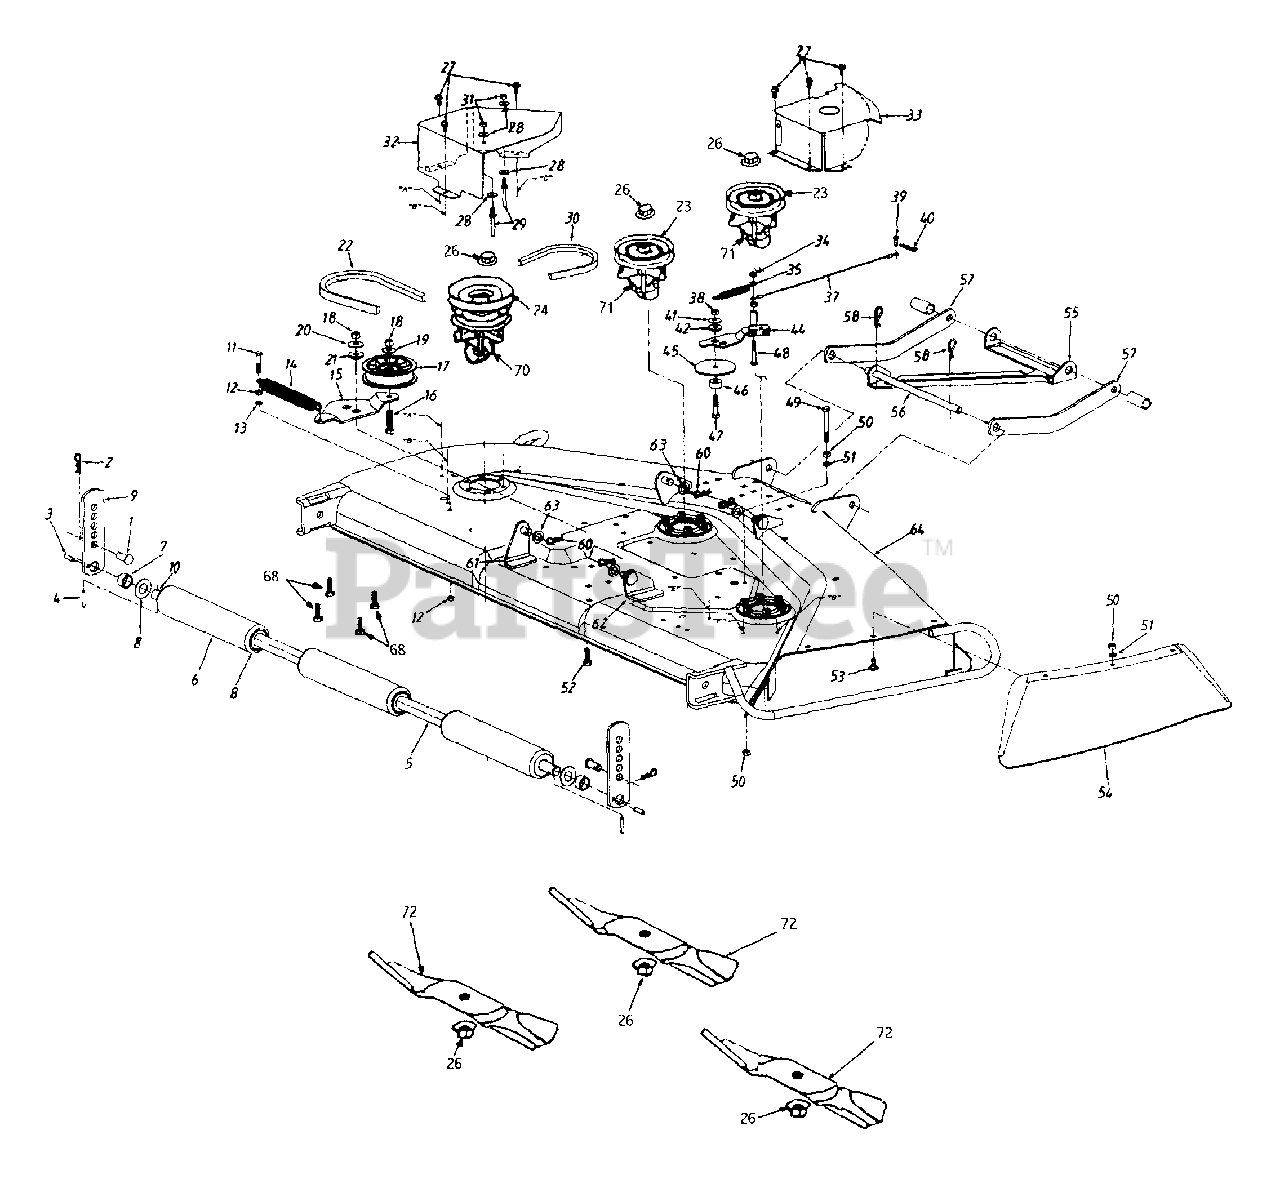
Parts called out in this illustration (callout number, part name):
1	Clevis Pin
2	Hairpin Clip
3	Spring Pin 1/4" x 1" Lg.
4	Spring Pin 3/16" x 1-1/4" Lg.
7	Spacer .75" I.D.
8	Fl-Wash. .76" I.D. x 1.5" O.D.
10	Roller Shaft
11	Hex Bolt 1/4-28 x 1.5" Lg. (Gr. 5)
12	Hex Nut 1/4-28 Thd.
13	L-Wash. 1/4" I.D.
14	Ext. Spring 7.33" Lg.
17	Idler Pulley
18	Hex Nut 3/8-24 Thd.
19	Bell-Wash. 3/8" I.D.
20	Bell-Wash. .39" I.D. x 1.13" O.D.
21	Shld. Spacer .625" I.D.
22	Lower "V" - Belt
23	Deck Pulley
24	Double Deck Pulley
26	Hex Flange Nut 5/8-18 Thd.
27	Hex Wash. Hd. Scr. 1/4-20 x .5" Lg.
28	Bell-Wash. 1/4" I.D.
29	Belt Guard Pin
30	Upper "V" - Belt
31	Hex Nut 1/4-20 Thd.
35	Ext. Spring 3.97" Lg.
37	Brake Cable
38	Hex Nut 5/16-24 Thd.
39	Clevis Pin
40	Hairpin Clip
41	Bell-Wash. .325" I.D.
42	Shld. Spacer
44	Brake Ass'y.
45	Fl-Wash. 5/16" I.D. x .3" O.D.
46	Spacer .44" Lg.
47	Hex Bolt 5/16-24 x 1.5" Lg. (Gr. 5)
48	Hx Bolt 1/4-28 x 1.75" Lg. (Gr. 5)
49	Hex Bolt 5/16-18 x 2.5" Lg.
50	Hex Nut 5/16-18 Thd.
51	L-Wash. 5/16" I.D.
52	Hex Bolt 3/8-24 x 1" Lg.
53	Carr. Bolt 5/16-18 x .75" Lg.
60	Hairpin Clip
63	Fl-Wash. 1/2" I.D. x .93" O.D.
70	Spindle Ass'y. (L.H.)
71	Spindle Ass'y. (R.H. & Center)
72	Blade
12649-0638	GUARD-CHUTE - MTD/TROY-BILT RED (0638)
12649-0648	GUARD-CHUTE - TECH GRAY (0648)
12650-4008	Height Adjuster - WINE RED (4008)
